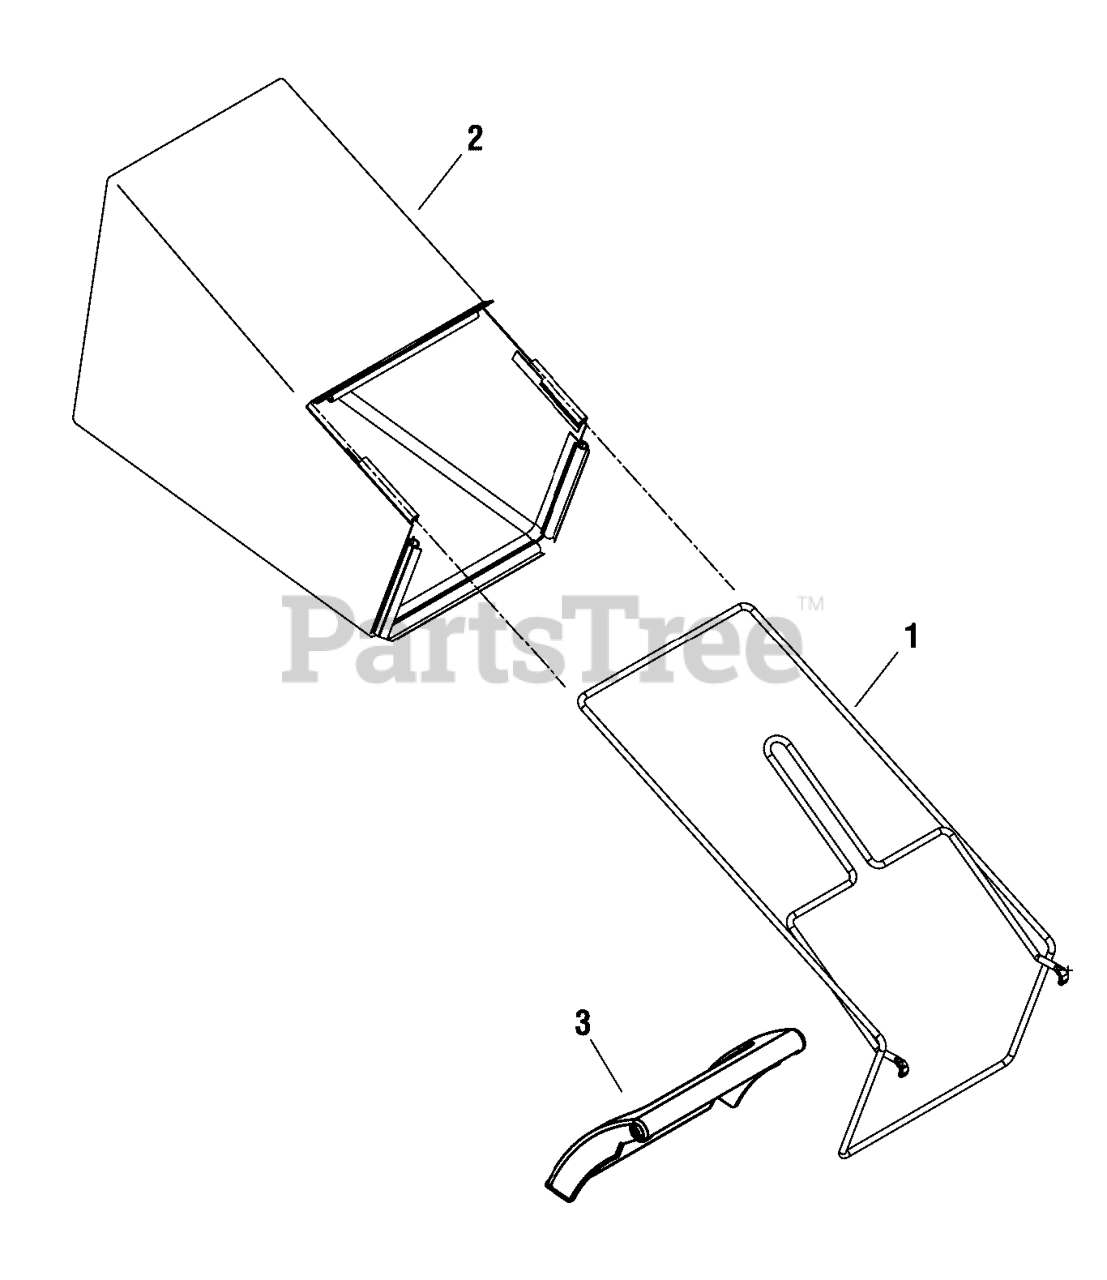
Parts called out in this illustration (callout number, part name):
1	FRAME ASSEMBLY
2	BAG ASSEMBLY
3	DOOR, Rear
